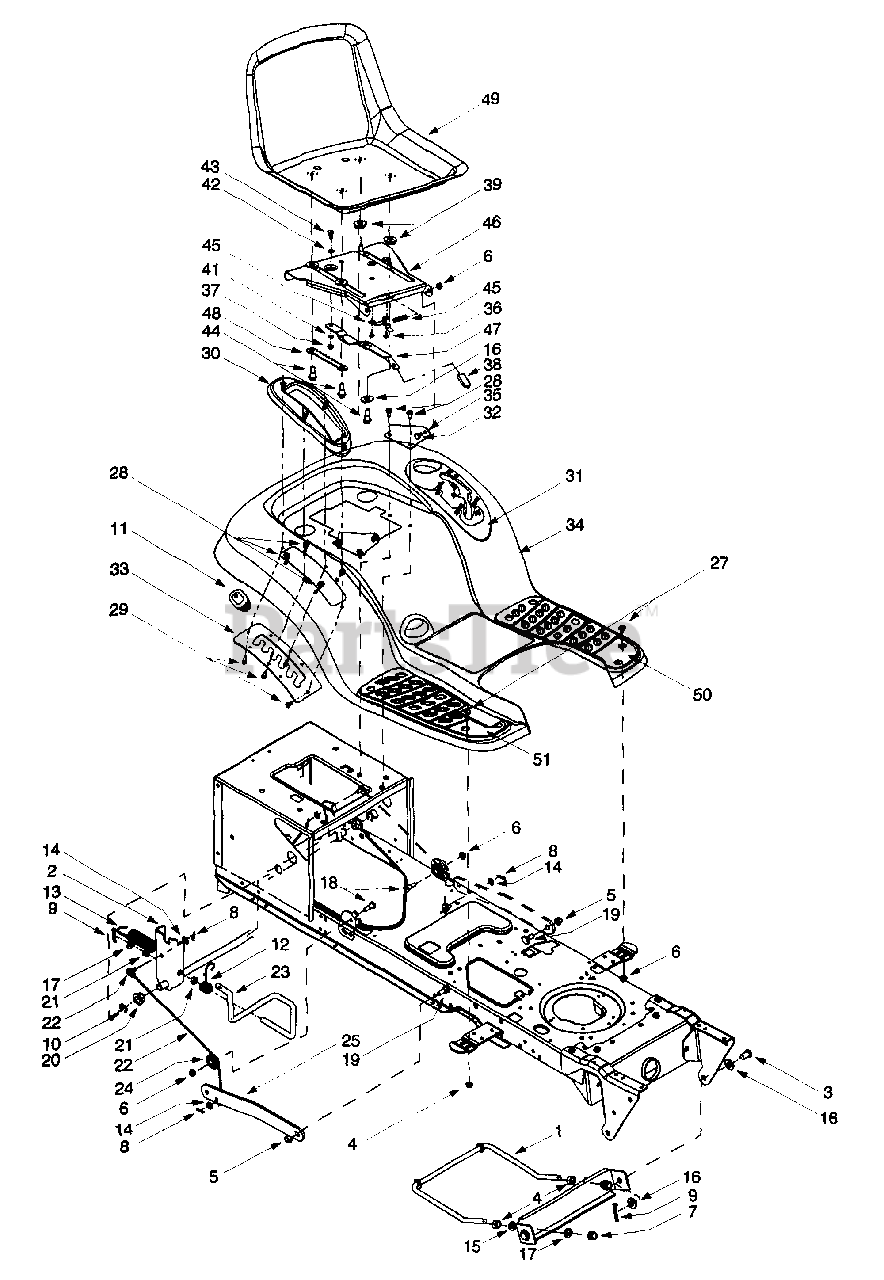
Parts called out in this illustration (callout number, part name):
1	Deck Stabilizer Rod
3	Clevis Pin, .5 x .78
4	Hex Nut, 1/2-13
5	Flange Lock Nut, 3/8-16
6	Flange Lock Nut, 5/16-18
7	Hex Nut, 1/2-13
8	Internal Cotter Pin
9	Cotter Pin
10	E-ring
11	Handle Grip
12	Torsion Spring
13	Lift-assist Spring, 1.15 x 5.99
14	Flat Washer, 5/16
15	Lock Washer, 1/2
16	Flat Washer, .31 x 1.062 x .134
17	Flat Washer, .51 x 1.12 x .06
18	Hex Cap Screw, 5/16-18 x .62
19	Shoulder Screw, .5 x .27, 3/8-16
20	Hex Range Bearing
21	Snap Flange Bearing
22	Lift Cable, 16.16
23	Lift Handle
24	Roller Pulley
27	Carriage Bolt, 5/16-18 x .62
28	Self Tapping Screw, 5/16-18 x .625
29	Self Tapping Screw, 1/4-15 x .75
30	Lift Lever Cover
31	Shift Lever Cover w/ Cup Holder
32	Shoulder Screw, .437 x 1.62
36	Screw, #10-16 x .375
37	Hex Flange Lock Nut, 1/4-20
38	Seat Adjuster Grip
39	Spacer
41	Spring Washer, .265 x .562 x .025
42	Flat Washer, .344 x .62 x .03
43	Shoulder Screw, .340 x .285, 1/4-20
44	Shoulder Screw, .50 x .50, 3/8-16
45	Seat Stop
48	Seat Adjustment Selector
49	Seat, Radiant Yellow
50	LH Foot Pad
51	RN Foot Pad
